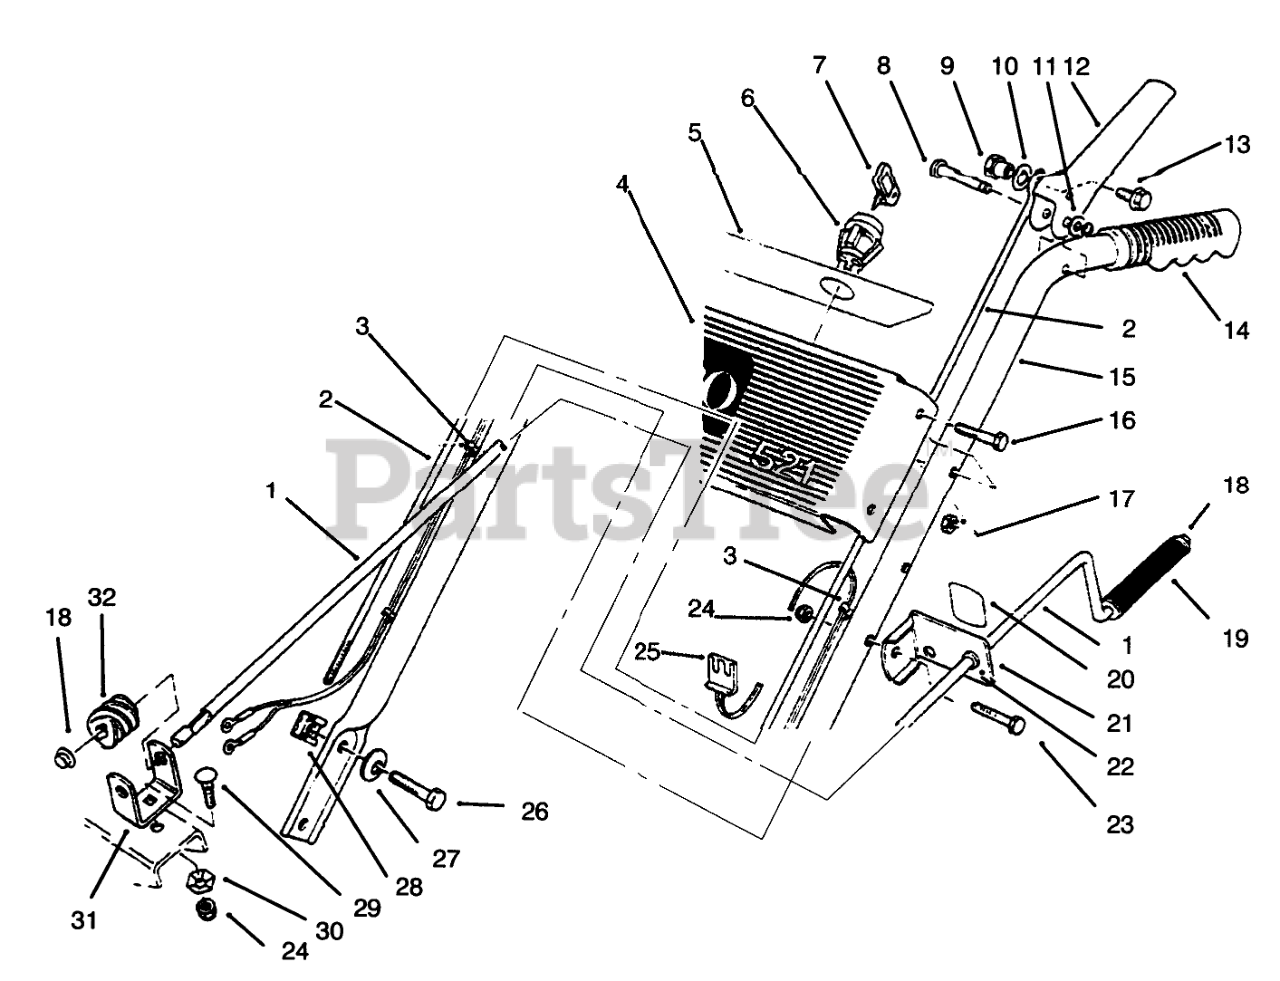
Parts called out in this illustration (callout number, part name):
1	ROD-CONTROL, CHUTE
2	LINK-UPPER
3	Mount-Wire
4	Reference Panel-Escutcheon
5	DECAL - ESCUTCHEON BACK
6	SWITCH
7	KEY-IGNITION
8	PIN-LEVER, CONTROL
9	POST-MOUNTING, LINKAGE
10	WASHER-FLAT
12	HANDLE-CONTROL
13	SCREW-HHF
14	GRIP-HANDLE
15	Handle-Left
16	SCREW-HH
17	NUT-LOCK, NI
18	RETAINER-PUSH ON
19	GRIP-CONTROL, CHUTE
20	DECAL-CHUTE DIRECTION
21	Bracket-Chute Control (Incl. Ref.# 20 & 22)
22	Bushing
23	SCREW-HH
24	NUT-LOCK, NI
25	Wire Harness Asm. (Incl. Ref.# 3)
26	SCREW-HH
27	WASHER-BELLEVILLE
29	SCREW-CARR
30	WASHER-LOCK
31	BRACKET-WORM
32	GEAR-WORM, CHUTE
